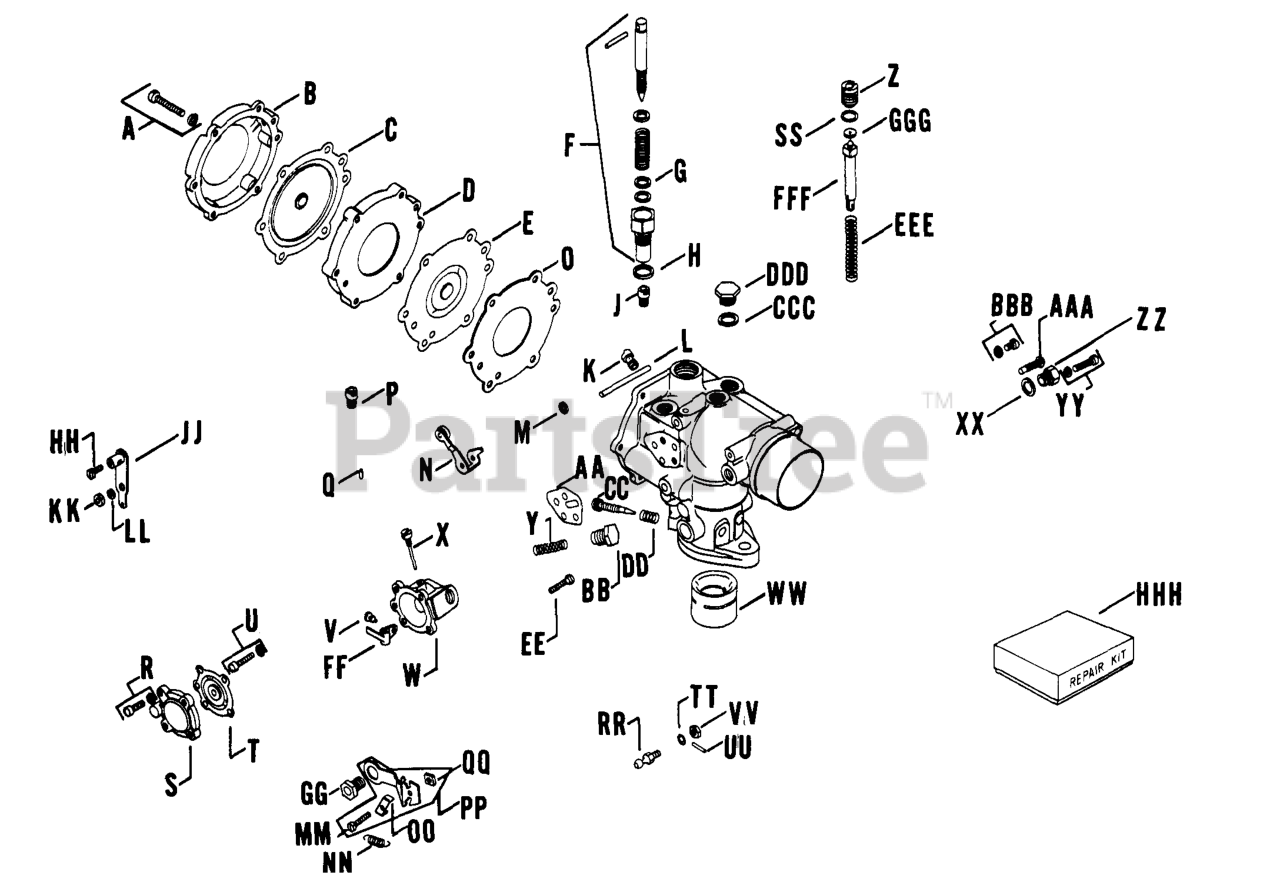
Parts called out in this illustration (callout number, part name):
C	DIAPHRAGM - DISCONTINUED
E	KIT - USE 277896
F	JET - DISCONTINUED
H	KIT - USE 277896
L	KIT - USE 277896
M	WASHER - DISCONTINUED
N	Lever, diaphragm
O	KIT - USE 277896
P	SCREW - DISCONTINUED
CC	KIT - USE 277896
DD	KIT - USE 277896
JJ	LEVER - DISCONTINUED
KK	NUT - DISCONTINUED
LL	WASHER, SPRING LOCK #10
NN	SPRING - DISCONTINUED
OO	CLIP - DISCONTINUED
PP	BRACKET - DISCONTINUED
RR	JOINT - DISCONTINUED
ZZ	PLUG - DISCONTINUED
